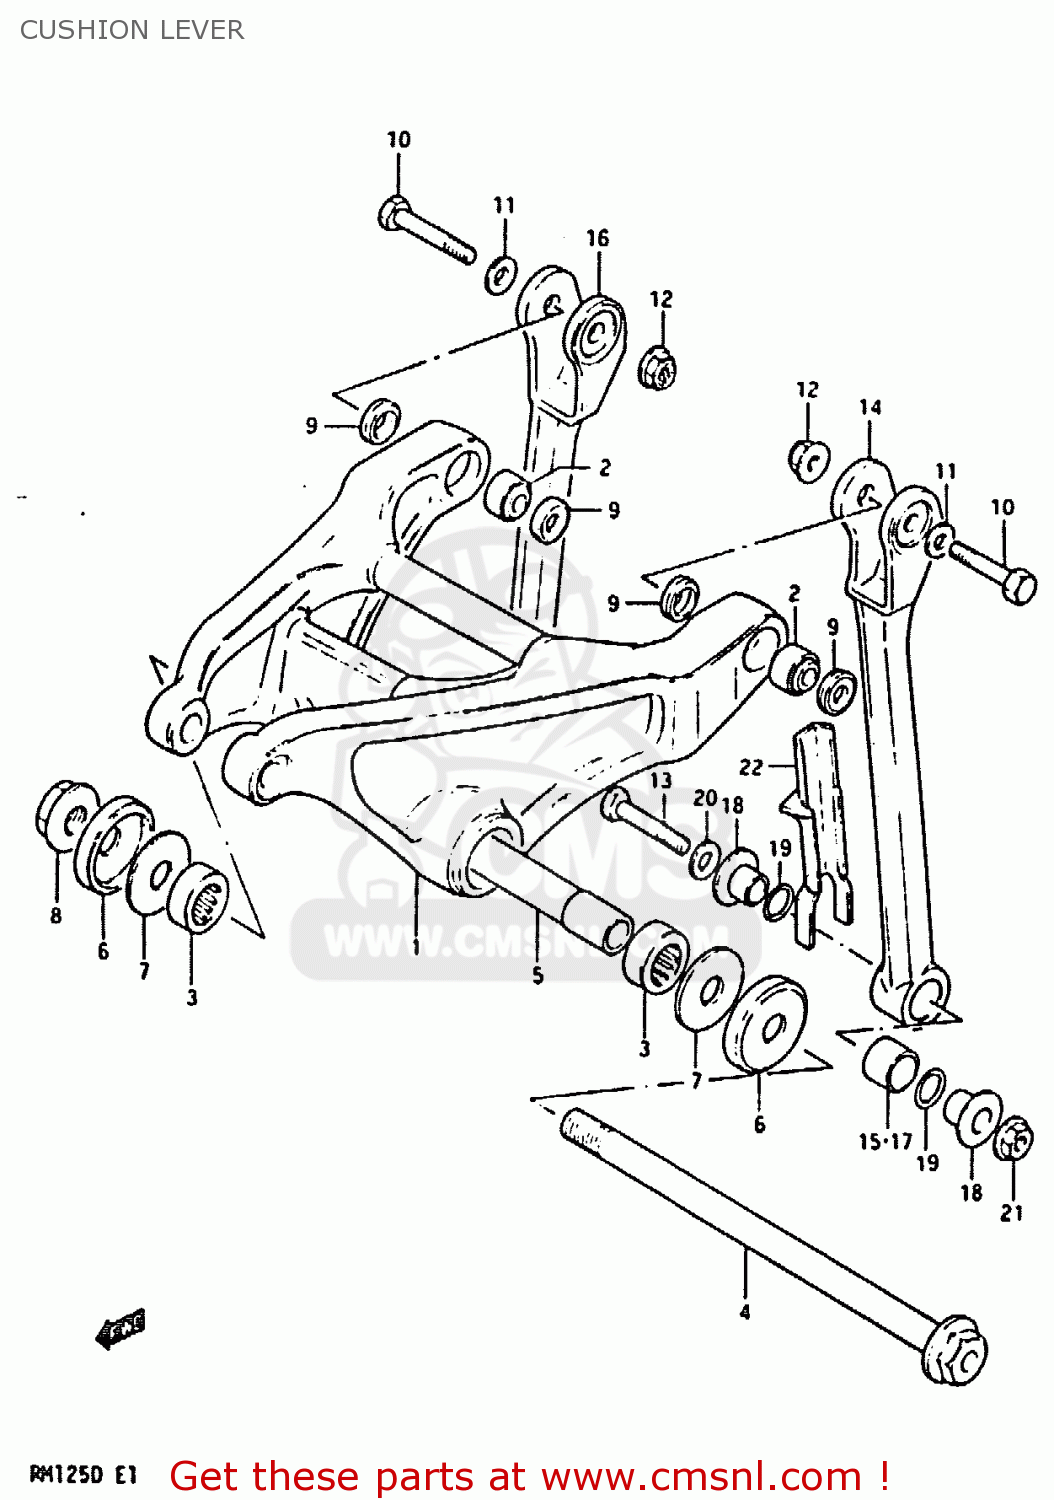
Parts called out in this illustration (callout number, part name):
1	LEVER SET,REAR CUSHION
2	BEARING(8X18X11)
3	BEARING(17X26X20)
4	SHAFT,REAR CUSHION LEVER
5	SPACER,REAR CUSHION LEVER
6	DUST SEAL
7	WASHER(12X35X2)
8	NUT 12MM
9	DUST SEAL,RR CUSHION LOD UPR
10	BOLT,REAR CUSHION LEVER
11	WASHER
12	NUT
13	BOLT,REAR CUSHION LEVER
14	LEVER SET,REAR CUSHION
15	BUSHING
16	LEVER ASSEMBLY,REAR CUSHION
17	BUSHING
18	SPACER,RR CUSHION ROD LWR
19	DUST SEAL,REAR CUSHION
20	WASHER
21	NUT
22	PROTECTOR,REAR CUSHION R
